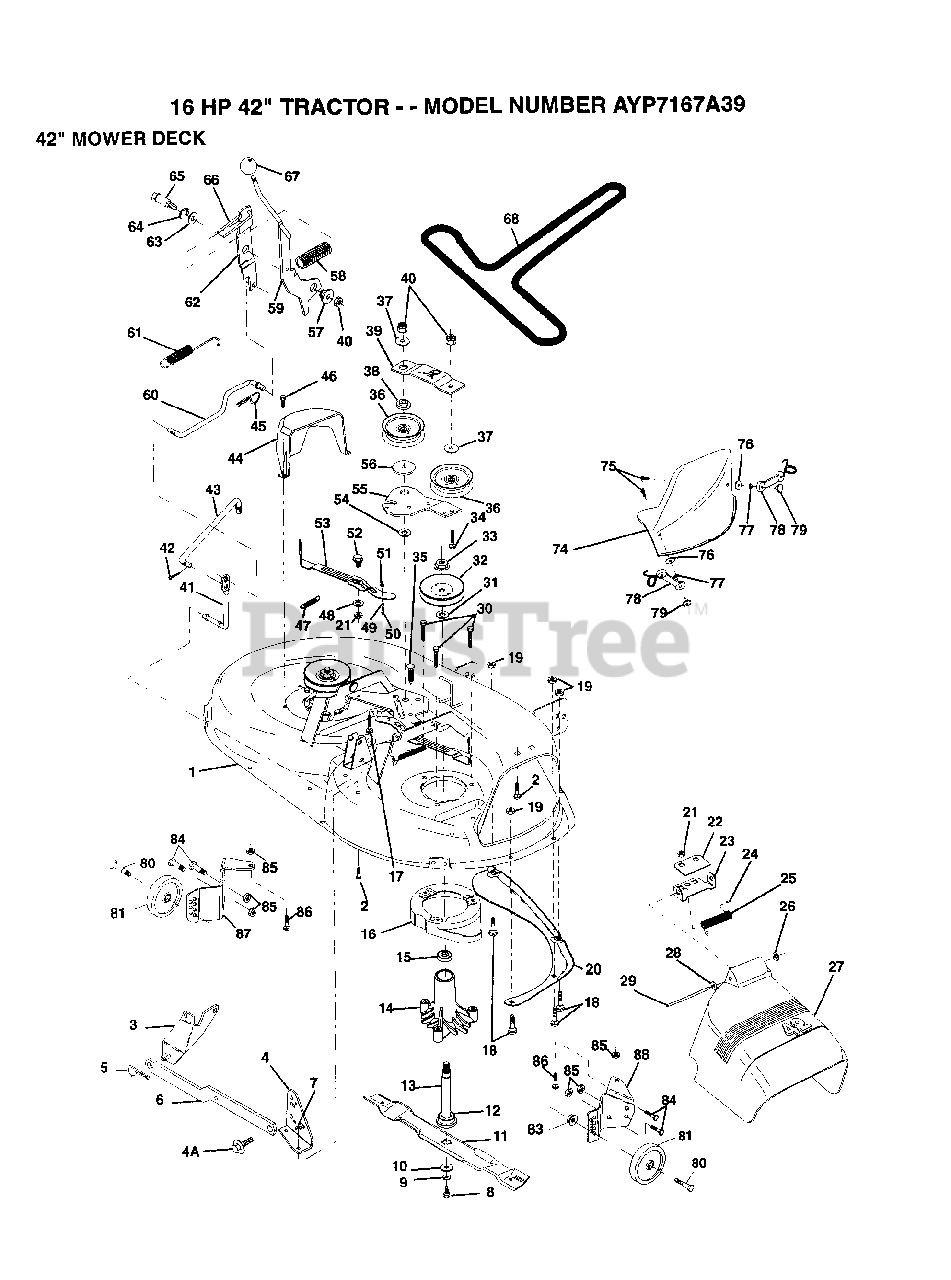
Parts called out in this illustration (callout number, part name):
2	BOLT
3	BRKT ASM SWAY BAR
4	BRKT SWAY BAR
4A	BOLT SHD 5/16-18
7	NUT
8	BLADE BOLT
10	WASHER BLADE
11	"BLADE.42"" MULCHER"
12	BEARING.BALL
14	HSG ASM MANDREL
15	BEARING
17	BOLT CARRIAGE
18	BOLT
19	NUT
22	STIFFENER BRKT
23	DEFLECTOR BRKT
24	CAP-SLEEVE LT
25	SPRING TORSION
26	NUT PUSH M
27	DEFLECTOR.SHIELD
28	WASHER
29	HINGE ROD
31	WASHER
34	BOLT
35	XMAS TREE FASTNER
36	FLAT IDLER PULLEY
37	WASHER GT
38	RETAINER SPACER
39	IDLER ARM STIFF
41	PIVOT ROD
43	CLUTCH ROD SECOND
45	RETAINER M
46	SCREW LT
47	SPRING EXTENSION
48	HARD SMALL WASHER
50	SHOULDER BOLT
51	LOCKNUT
53	BRAKE PAD ARM ASM
54	HARDENED WASHER
55	IDLER ARM
56	SPACER RETAINER
57	BUSHING
60	"ROD, CLUTCH PRIM"
61	RETURN SPRING
62	CLUTCH ARM SECOND
63	WASHER
64	RING
65	SHOULDER BOLT
66	SPRING KEEPER
68	BELT-V.92.4.MWR
74	"COVER.MULCH.42"""
75	WASHER #10
76	LOCKWASHER
77	SCREW
81	WHEEL GAGE DONUT
83	NUT SPECIAL T
84	BOLT
